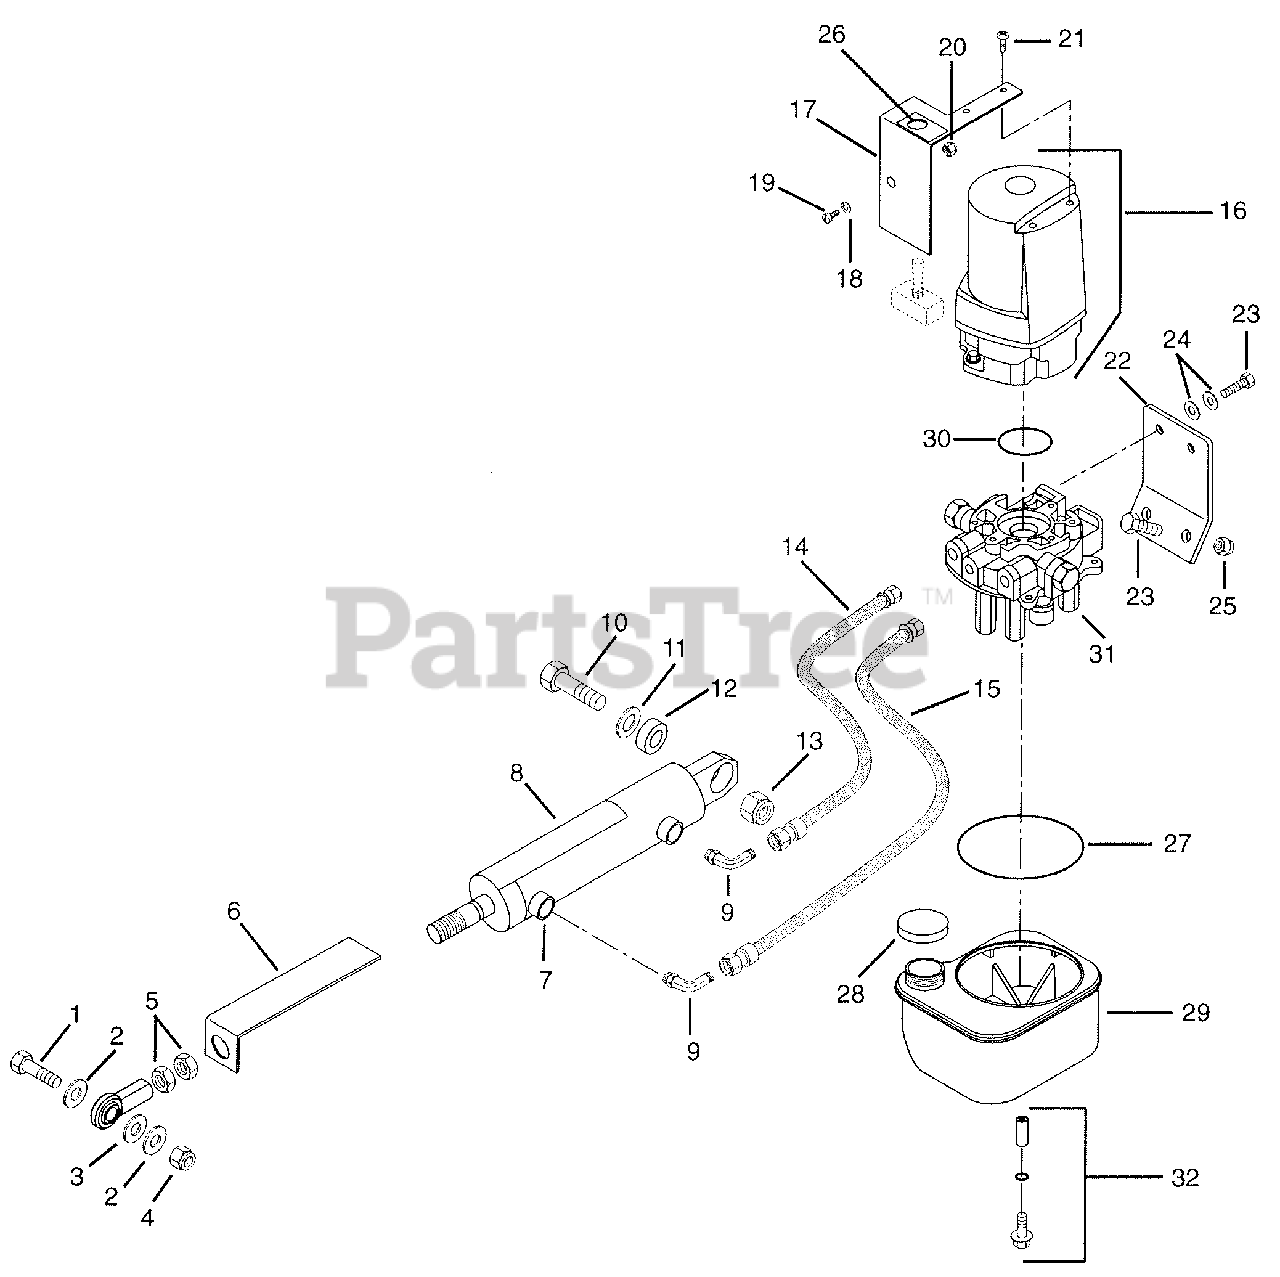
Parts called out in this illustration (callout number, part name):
1	Bolt Hex .50-13 X 1.25 Grade 2
2	Washer Flat Steel .625 X 1.375 X .109
3	Rod End, 5/8" Female
4	Nut Locking Nylon .625-11 Grade 2
5	Nut Jam .625-18
6	Strap Height of Cut Indicator
7	Cylinder, Hydraulic Lift
8	Decal Height of Cut
9	Adapter 2503-4-4
10	Bolt Hex .50-13 X 2.25 Grade 5
11	Washer Flat Steel .531 X 1.250 X .100
12	Bushing, .516 X 1.000 X 1.050
13	Nut Locking Nylon .50-13 Grade 2
14	Assembly, Hose Pump to Cylinder
15	Assembly, Hose Pump to Cylinder
16	Motor Assembly
17	Switch Plate, Lift Pump
18	Washer Flat Steel .281 X .625 X .065
19	Screw Machine .25-20
20	Nut Locking Nylon .250-20 Grade 2
21	Screw Tapping 12-14 X .50
22	Lift Pump Mounting Bracket
23	Bolt Hex .38-16 X .75 Grade 5
24	Washer Flat Steel .406 X .812 X .065
25	Nut Locking Nylon .375-16 Grade 2
26	Decal, Cutting Head Treated Adjustment
27	Reservoir Seal, O-Ring
28	Reservoir Cap
29	Reservoir Tank
31	Adapter Assembly
32	Screw, O-Ring and Spacer Assembly
NS	Seal/O-Ring Kit
